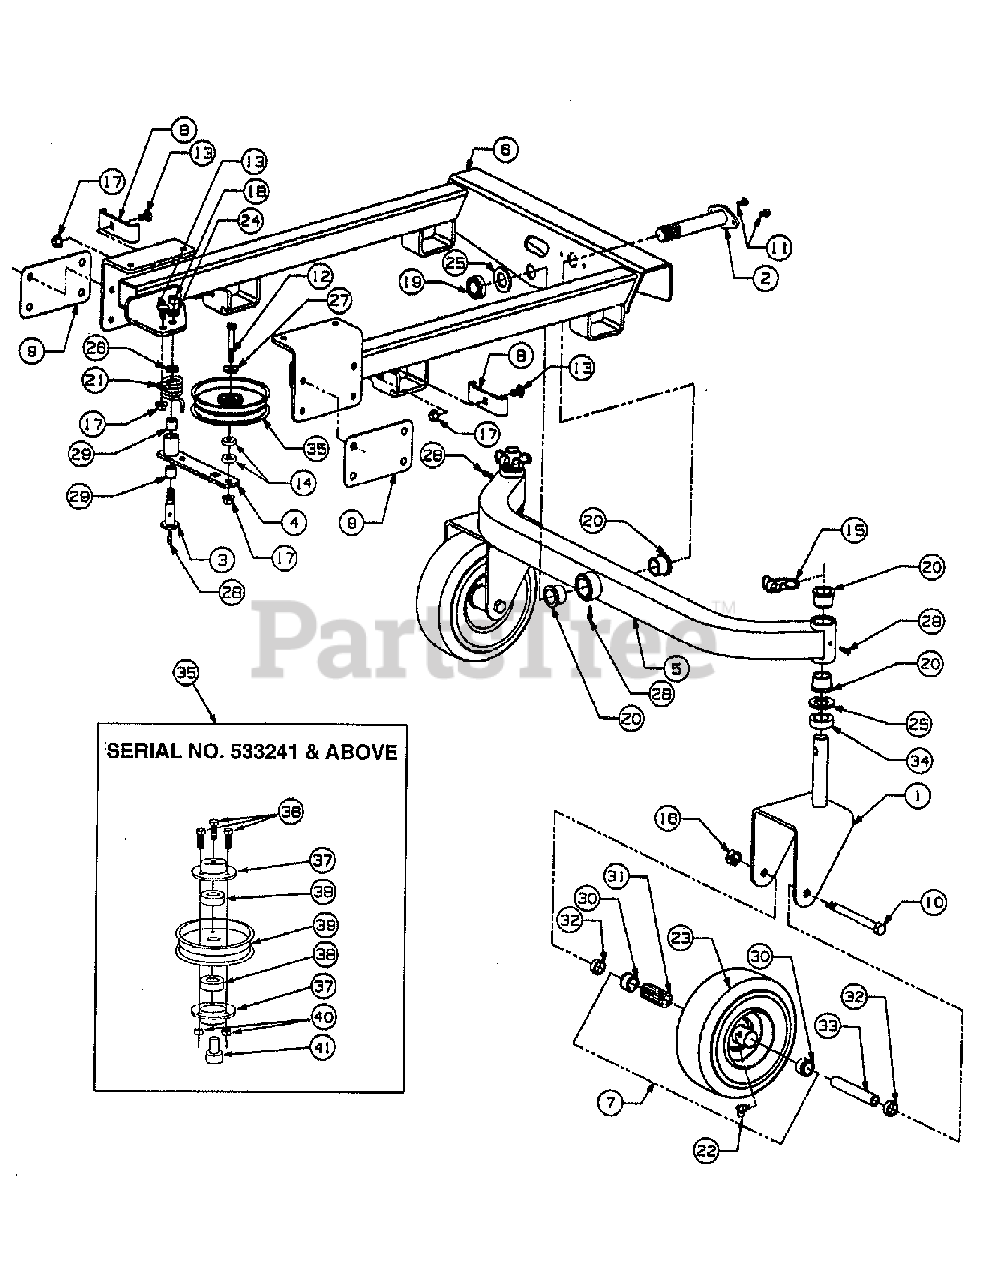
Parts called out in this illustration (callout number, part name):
2	Pin, Axle Pivot
3	Bolt, Shoulder
4	Arm Assembly, Idler
5	Axle Assembly, Front
6	Nut, Hex Flanged Lock 3/8-16
7	Wheel Assembly, Caster
8	Stop, Wear Bar
10	Screw, Hex Cap, 1/2-20 x 5.50
11	Screw, Hex Wash Hd Tapp 1/4-20 x .50
12	Screw, Hex Cap, 3/8-16 x 2.5 Gr 5
13	Bolt, Sht Nk Carriage, 3/8-16 x .75 Gr 5
14	Spacer, .38 x 1.0 x .32
15	Pin, Klik
16	Nut, Hex Center Lock, 1/2-20
17	Nut, Hex Flanged Lock, 3/8-16
18	Nut, Hex, 7/16-14 Gr 5
19	Nut, Hex Lock, 1-14
20	Bearing, Flange
21	Spring, Torsion
22	Fitting, Grease, 90 Deg, 1/4-28
23	Tire, Smooth, 9.0 x 3.70 x 4
24	Washer, Lock 7/16
25	Washer, Special
26	Washer, Flat .469 x .875 x .105 Thk
27	Washer, Flat .406 x 1.0 x .105 Thk
28	Fitting, Lube
29	Bearing, Sleeve
30	Bearing, Flange
31	Bearing, Roller
32	Spacer, .790 ID x .347
33	Spacer, Wheel
34	Spacer, 1.015 x 1.62 x .50
35	Pulley, 5'' Idler
35	Pulley Assembly, Idler
36	Screw, Hex Cap, 1/4-20 x .62 Gr 5
37	Cup, Bearing
38	Bearing, Ball
39	Pulley, 5'' Idler
40	Nut, Hx Insrt Lock 1/4-20
41	Spacer, Shoulder
